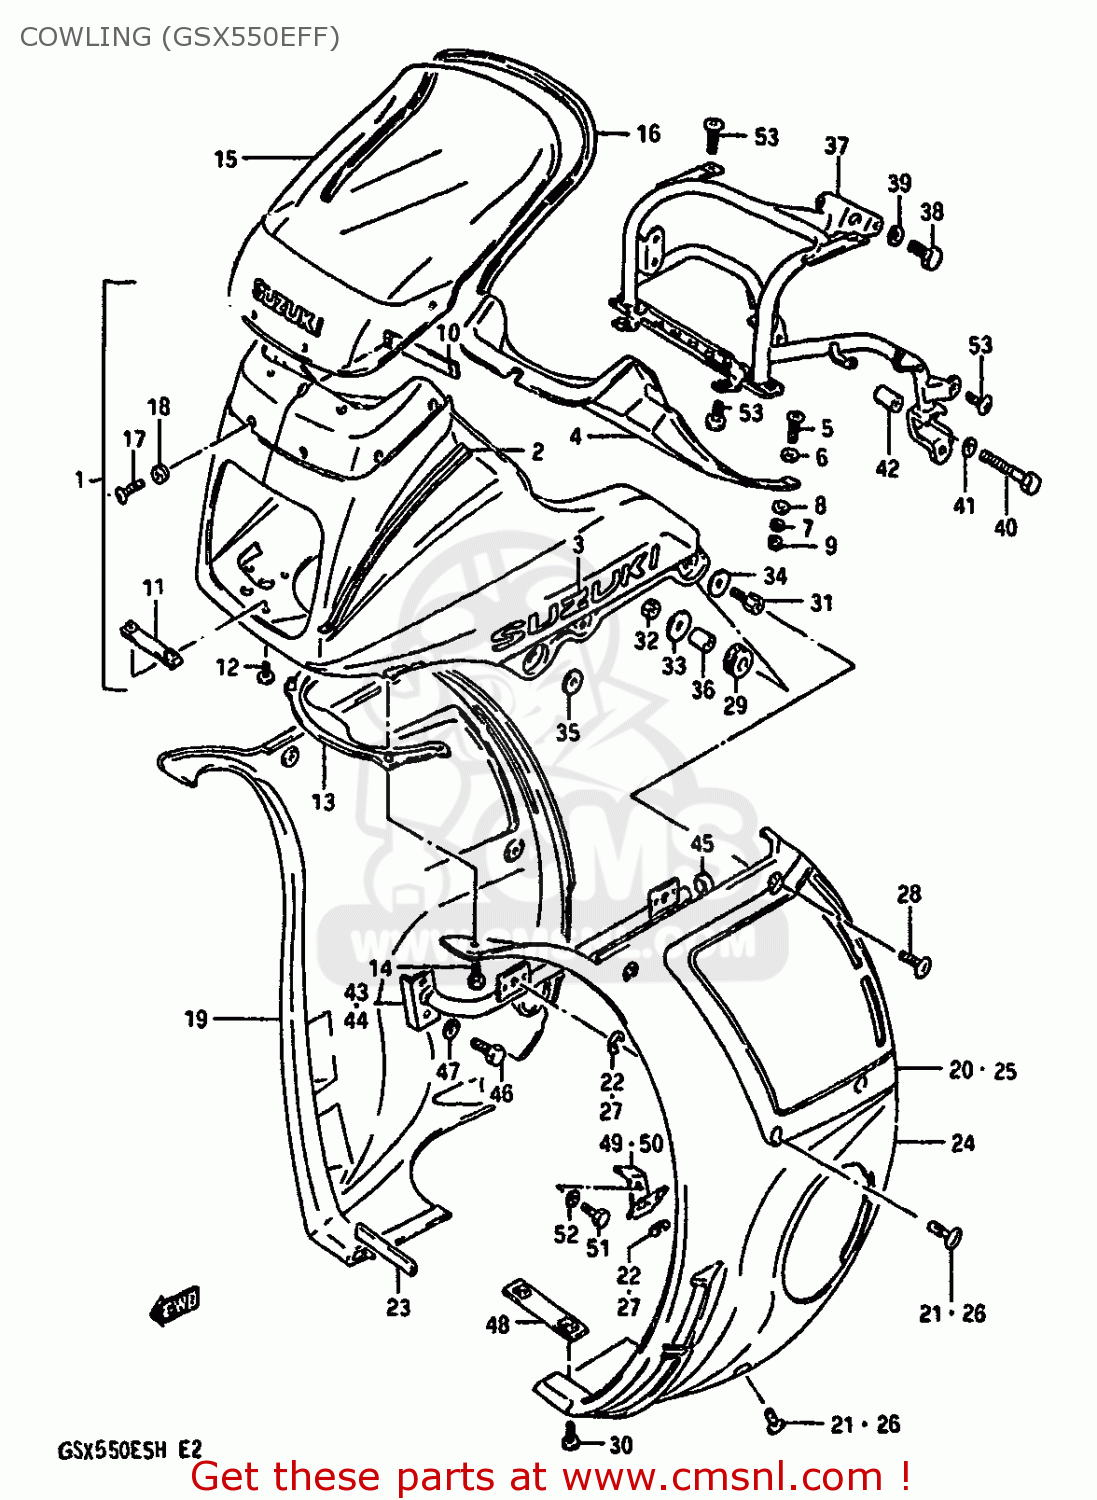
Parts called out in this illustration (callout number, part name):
1	COWLING ASSY (WHITE/RED)
2	TAPE SET
3	EMBLEM
4	PANEL,COWLING,UPPER
5	SCREW
6	WASHER,5MM
7	WASHER,LOCK
8	WASHER,5MM
9	NUT ,5MM
10	BRACKET,COWLING,UPPER
11	BRACKET,COWLING,LOWER
12	SCREW
13	COVER,COWLING,LOWER
14	SCREW
15	WINDOW
16	MOULDING
17	SCREW
18	CUSHION
19	COVER,COWLING
20	TAPE SET
21	FASTENER,COWL SIDE COVER
22	E-RING
23	MOLDING,LOWER
24	COVER,LH (WHITE/RED)
25	TAPE SET
26	FASTENER,COWL SIDE COVER
27	E-RING
28	SCREW,COWLING SIDE COVER
29	CUSHION
30	SCREW 6X12
31	BOSS,COWLING BODY,SIDE
32	NUT
33	WASHER (6.5X24X1.6)
34	WASHER, QUTER, REAR
35	WASHER(6.5X18X1)
36	SPACER (6.3X9.1X6.7)
37	BRACE,COWLING
38	BOLT
39	WASHER,LOCK,8.
40	BOLT
41	WASHER,LOCK,8.
42	SPACER (8.2X12.5X23.5)
43	BRACE,COWLING SIDE,RIGHT
44	BRACE,COWLING SIDE,LEFT
45	CUSHION
46	BOLT
47	WASHER,LOCK
48	BRACE,COWLING,LOWER,FRONT
49	BRACKET,COWLING SIDE,RIGHT
50	BRACKET,COWLING SIDE,LEFT
51	BOLT
52	WASHER,LOCK
53	SCREW 6X12
